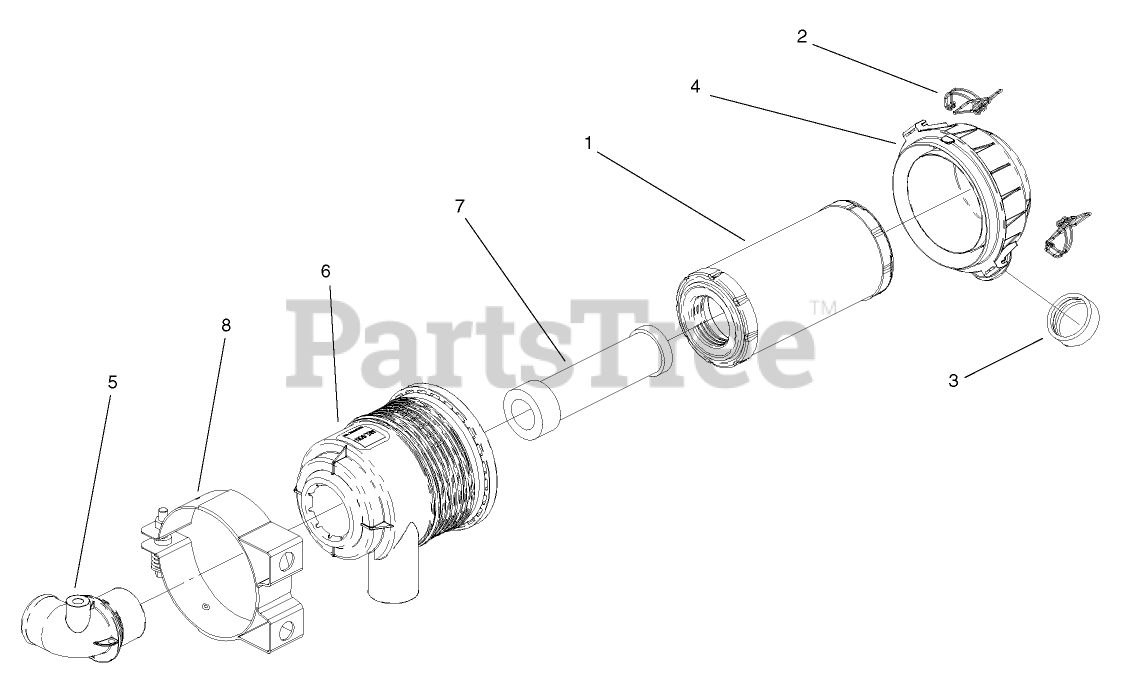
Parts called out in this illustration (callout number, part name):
1	ELEMENT-FILTER, AIR
2	CLIP-CLEANER, AIR
3	VALVE-EJECTOR, DUST
4	COVER
5	TUBE ASM
6	HOUSING
7	FILTER-SAFETY
8	MOUNTING BRACKET ASM
